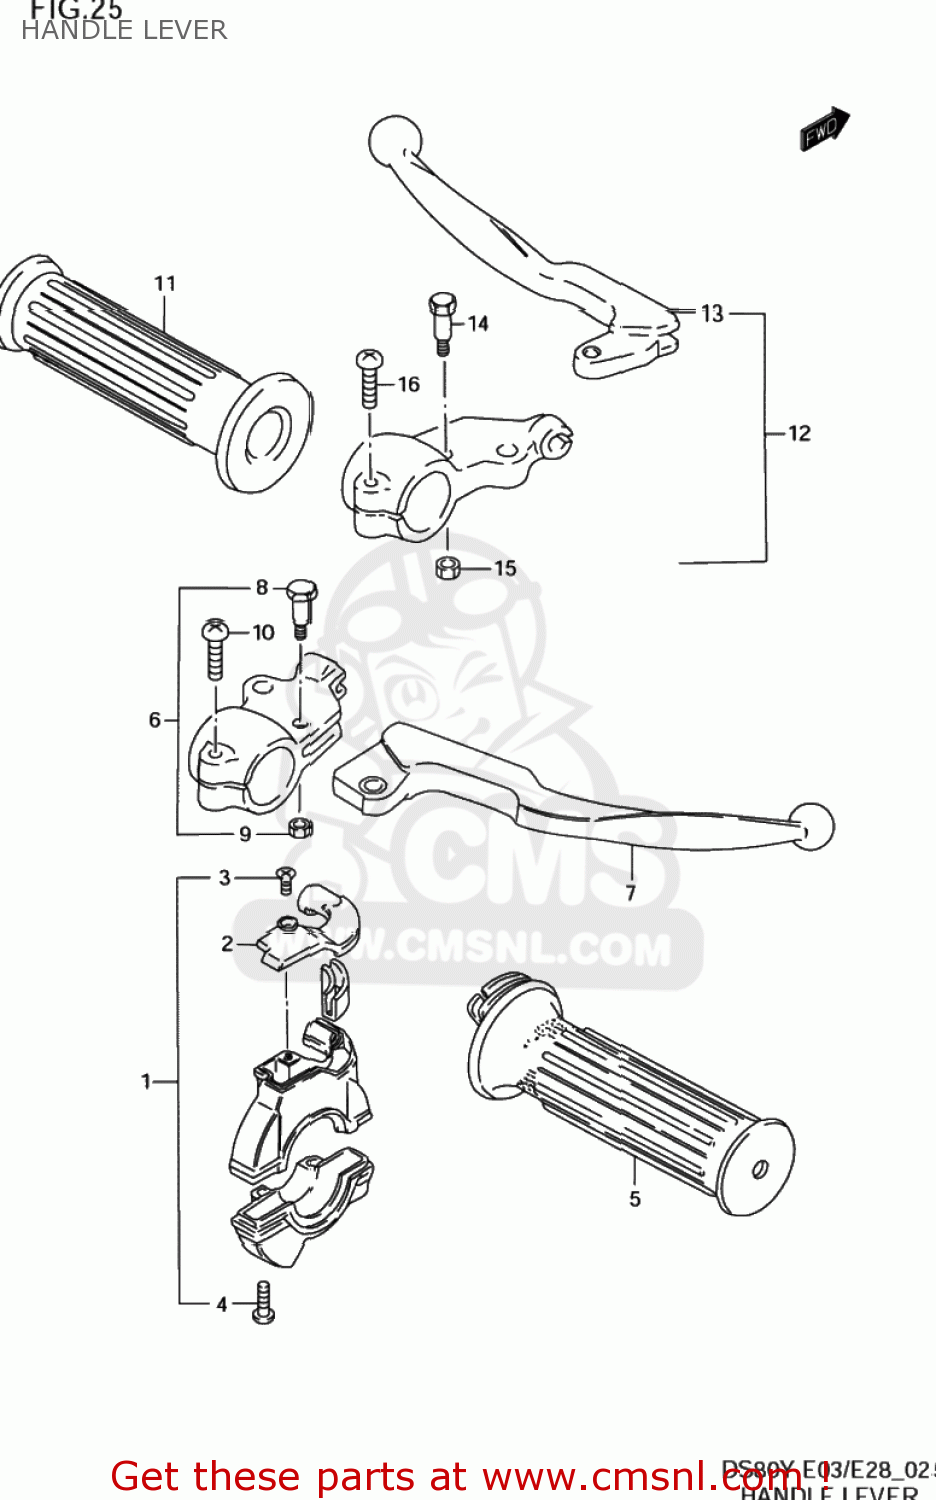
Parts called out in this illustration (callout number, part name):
1	CASE ASSY,THROTTLE
2	COVER,THROTTLE CASE
3	SCREW,UPPER
4	SCREW
5	GRIP,THROTTLE
6	LEVER ASSY,BRAKE
7	LEVER,BRAKE
8	SCREW
9	NUT
10	SCREW, 6X20
11	GRIP,L
12	LEVER ASSY,CLUTCH
13	LEVER,CLUTCH
14	SCREW
15	NUT
16	SCREW, 6X20
